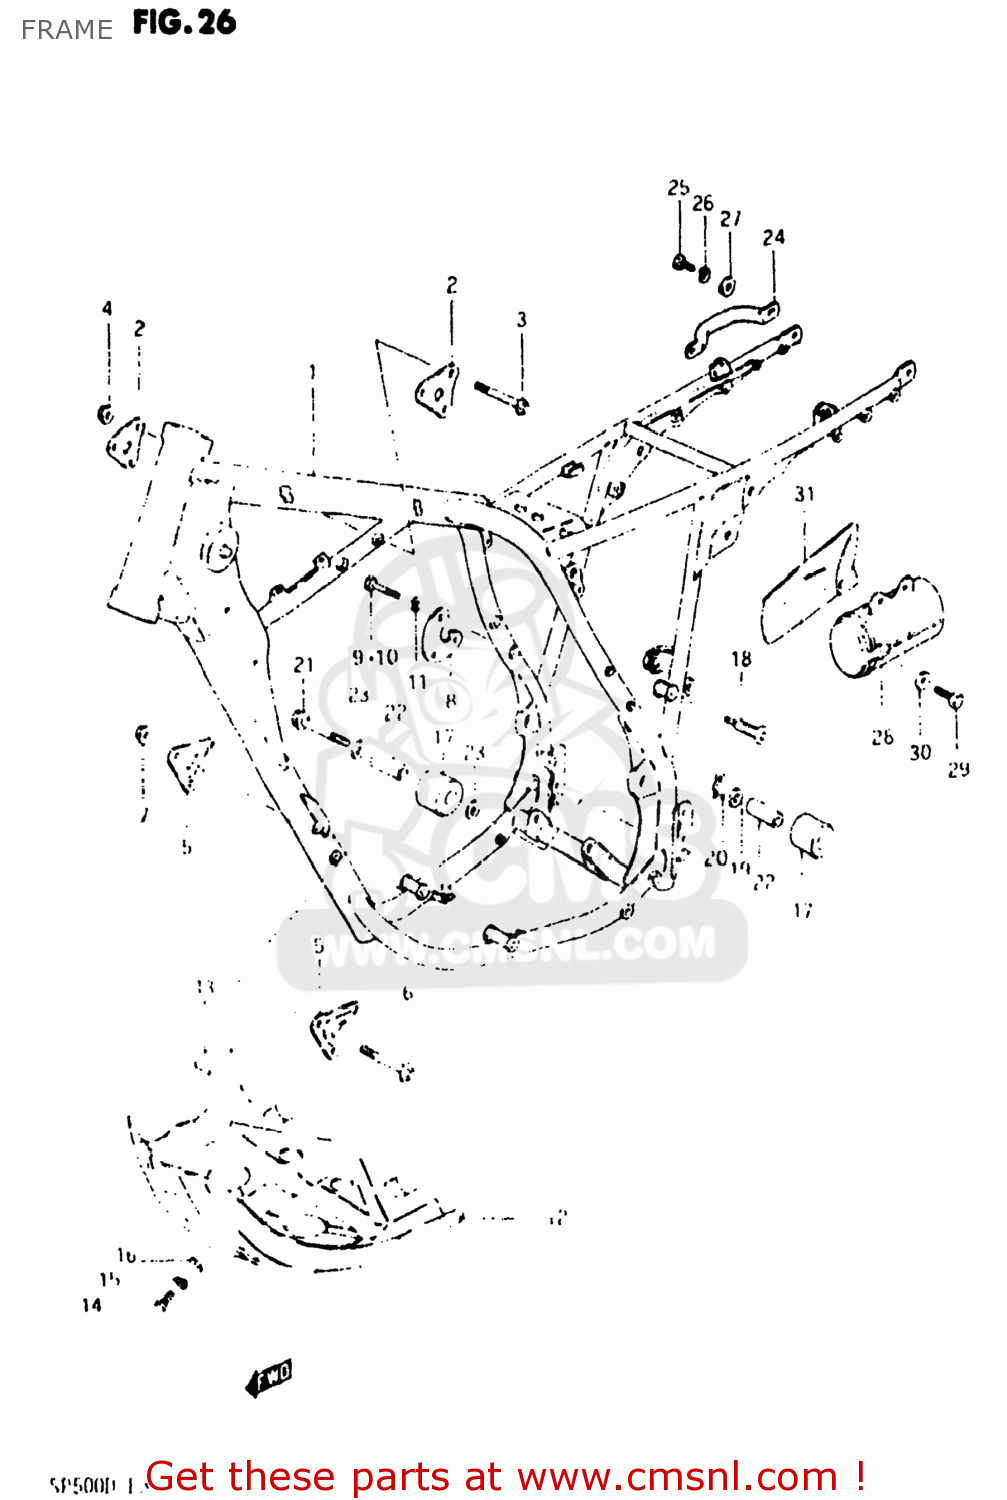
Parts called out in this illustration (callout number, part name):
1	FRAME
2	PLATE,ENGINE MOUNTING,UPPER
3	BOLT
4	NUT
5	PLATE,ENGINE MOUNTING,FRONT
6	BOLT 8X67
7	NUT
8	PLATE,ENGINE MOUNTING
9	BOLT
10	BOLT 8X50
11	LOCK WASHER
12	PLATE,ENGINE,UNDER
13	CUSHION,ENGINE,UNDER
14	BOLT
15	LOCK WASHER
16	WASHER
17	ROLLER,CHAIN LENGTH CONTROL
18	BOLT,CHAIN LENGTH ROLLER
19	WASHER
20	E RING 8MM
21	BOLT(8X45)
22	SPACER,CHAIN LENGTH ROLLER
23	WASHER
24	GRIP,FRAME HANDLE
25	BOLT
26	LOCK WASHER
27	WASHER
28	HOLDER,TOOL
29	BOLT, UPPER
30	WASHER (6.5X18X1.6)
31	TOOL SET
